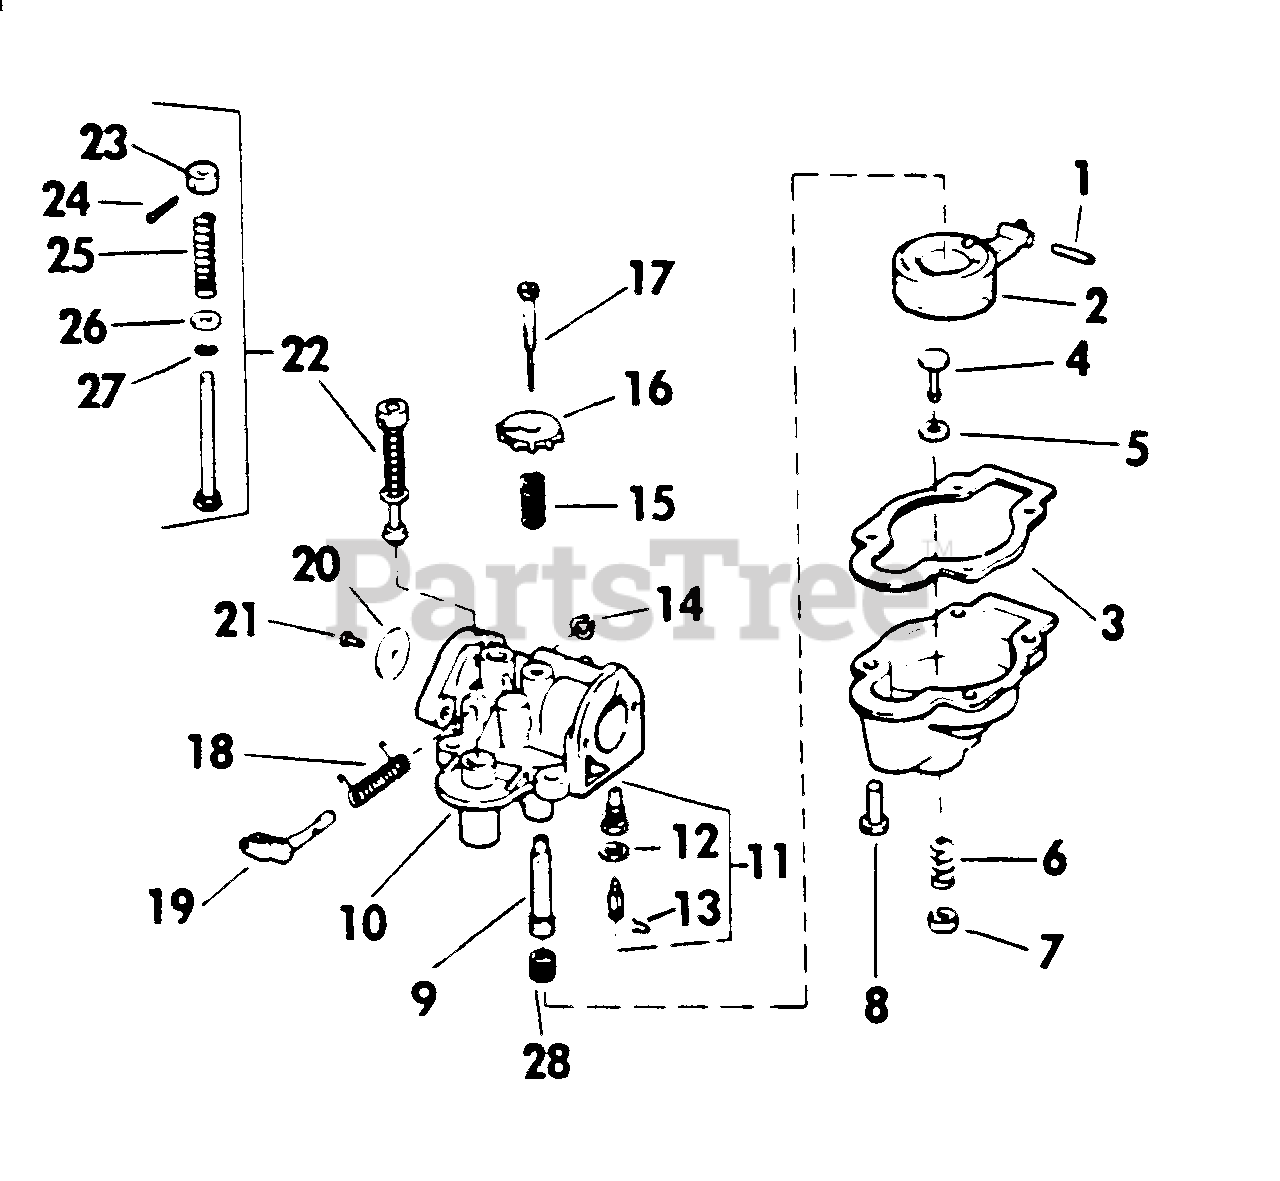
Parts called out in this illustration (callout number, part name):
1	Pin-Float Arm Hinge
2	Float and Arm Assy.
3	Gasket-Float Chamber
4	Valve Stem
5	Valve Seat
6	Valve Spring
7	Valve Keeper
8	Screw-Float Chamber
9	Nozzle
10	Carburetor Body Assy.
11	Float Valve & Seat
12	Washer-Float Valve Seat
13	Clip
14	Grip Ring
15	Spring-Needle Adj.
16	Knob-Needle Adj.
17	Needle Assy.
18	Spring-Throttle
19	Throttle Shaft & Lever Assy.
20	Disc-Throttle
21	Screw-Throttle Shaft Disc
22	Primer Assy.
23	Knob Primer
24	Cotter Pin
25	Spring Compression
26	Washer-Plain
27	"O" Ring
